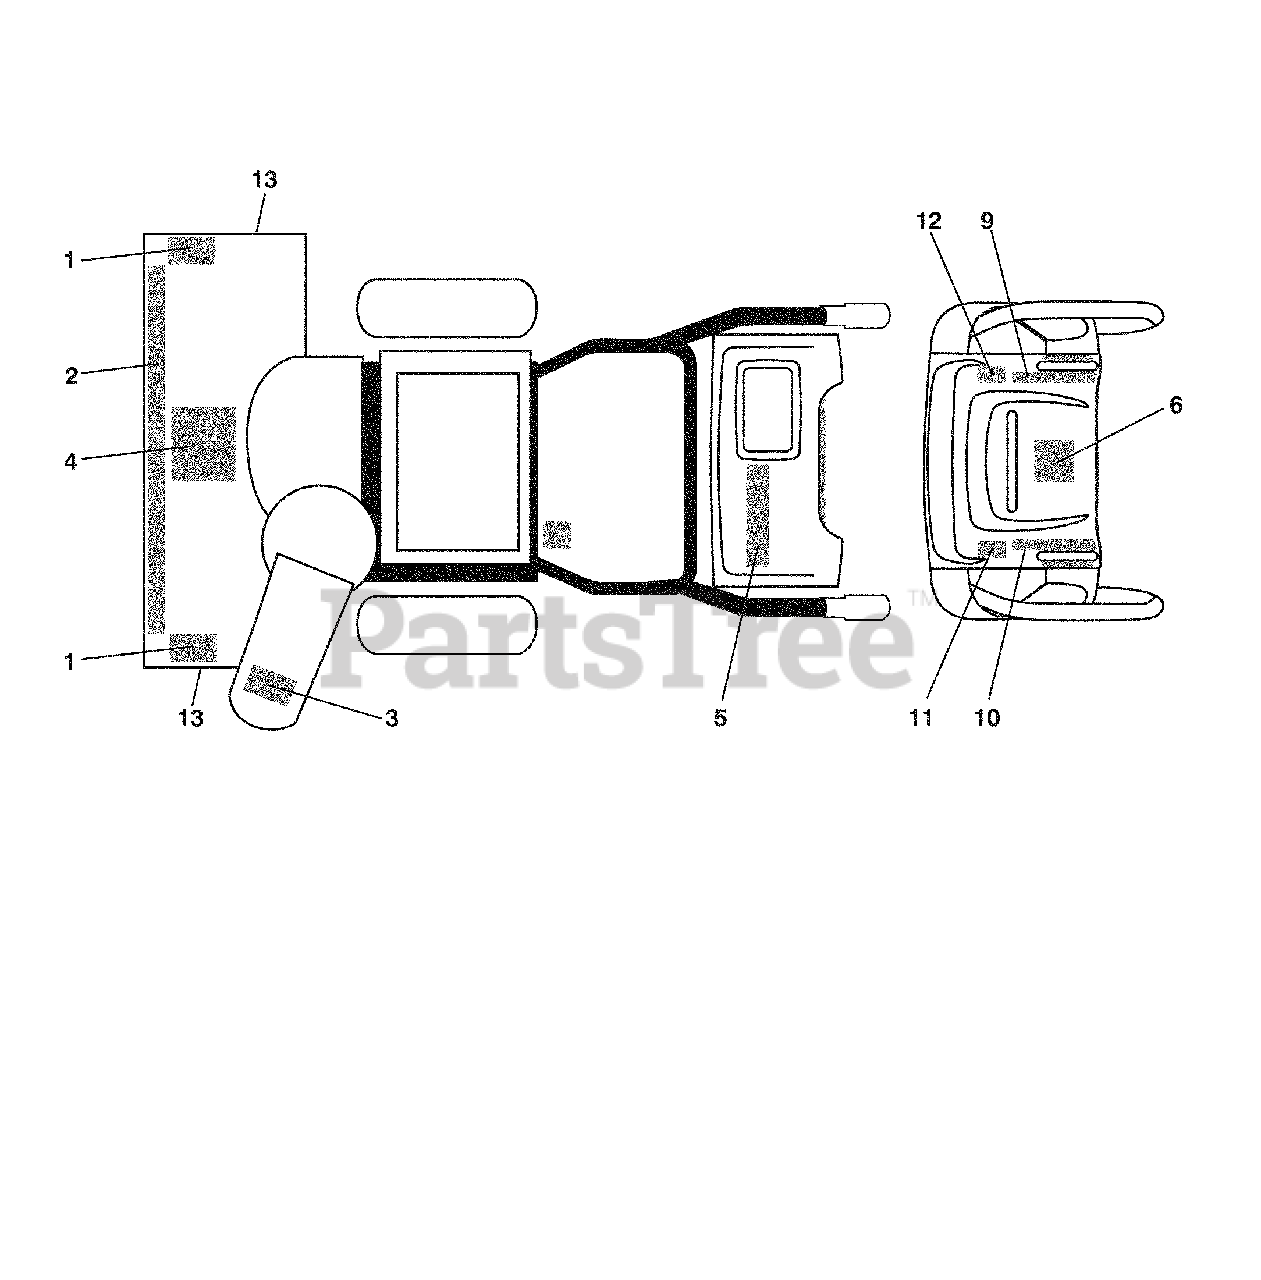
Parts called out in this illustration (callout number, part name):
1	Decal, Danger
2	Decal, Husqvarna
3	Decal, Danger, Deflector
4	Decal, Danger
5	Decal, Husqvarna, 1130SBE
6	Decal, Instruction
9	Decal, Speed Control
10	Decal, Remote Deflector
11	Decal, LH Trigger
12	Decal, RH Trigger
13	Decal, Husqvarna, Crown
